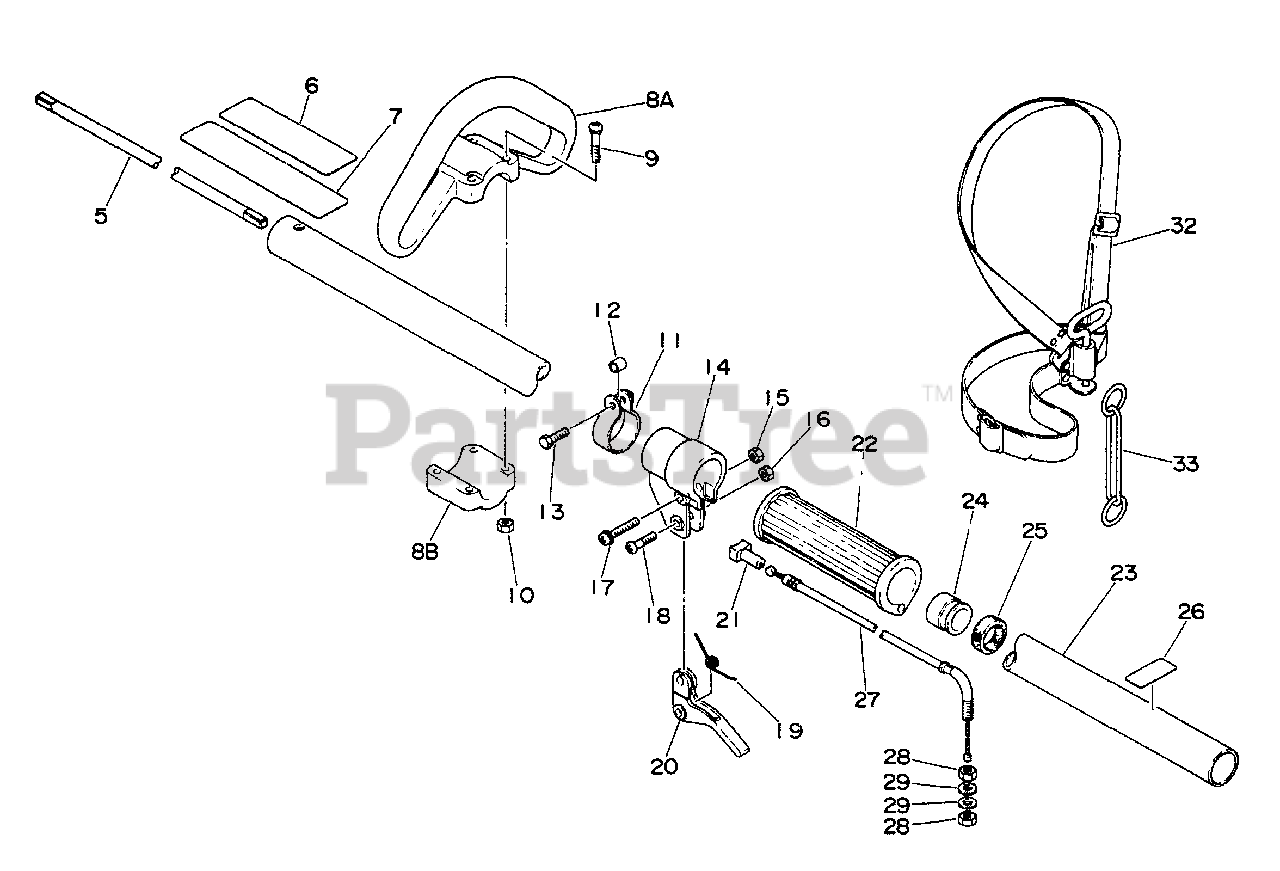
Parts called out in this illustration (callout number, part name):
5	DRIVESHAFT
7	LABEL - CAUTION
8	LOOP HANDLE ASSY
8A	LOOP HANDLE ASSY
8B	LOOP HANDLE ASSY
9	SCREW 5×35
10	NUT M5
12	SPACER, GUARD
13	BOLT 5×18
14	BRACKET, TRIGGER
15	NUT M5
16	LOCKNUT - 5
17	SCREW 5×30
19	SPRING, THROTTLE
20	TRIGGER, THROTTLE
21	GUIDE, CABLE
22	GRIP
23	MAIN PIPE ASSY
26	LABEL - ALIGNMENT
27	CABLE, THROTTLE
29	WASHER 6.5×11.5×0.8
32	SHOULDER STRAP ASSY
33	HOOK
